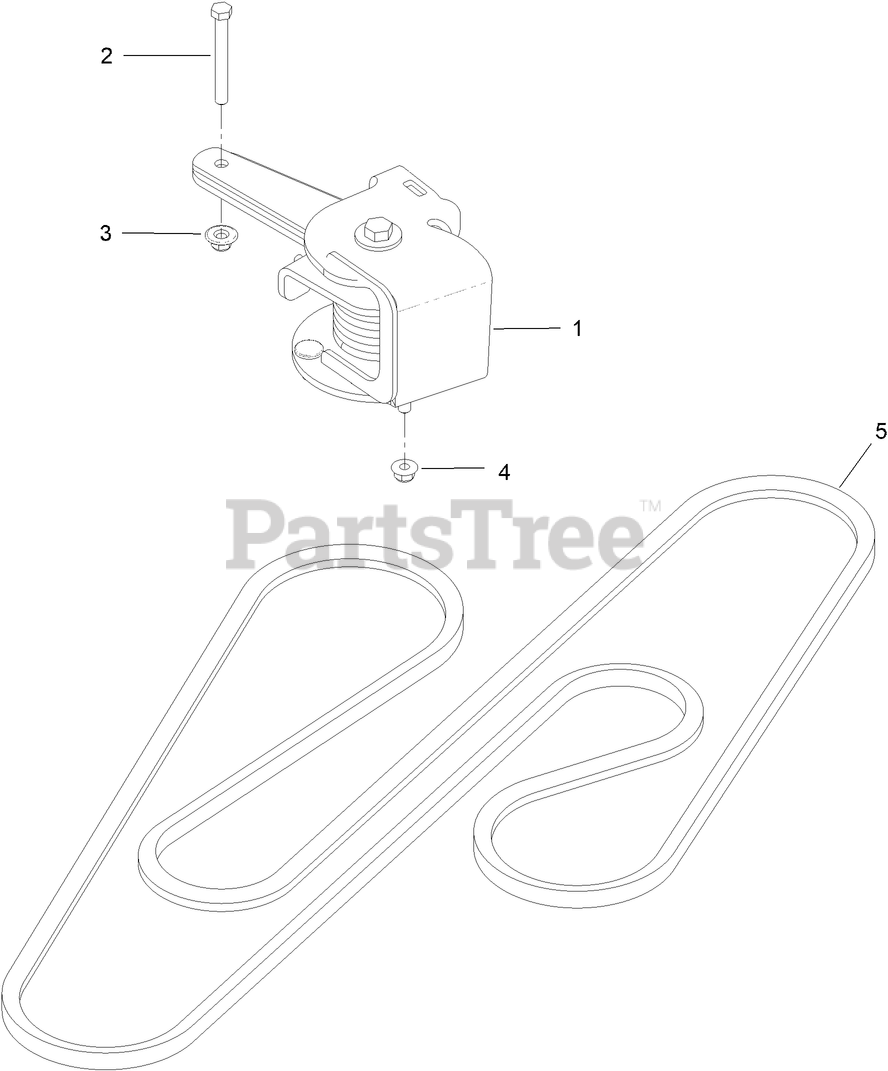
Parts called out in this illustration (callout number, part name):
1	GS TORSION IDLER ASM II
2	SCREW-HH
3	NUT-FLANGE, NI
4	NUT-HF, NI
5	GS 48 DECK BELT-V
